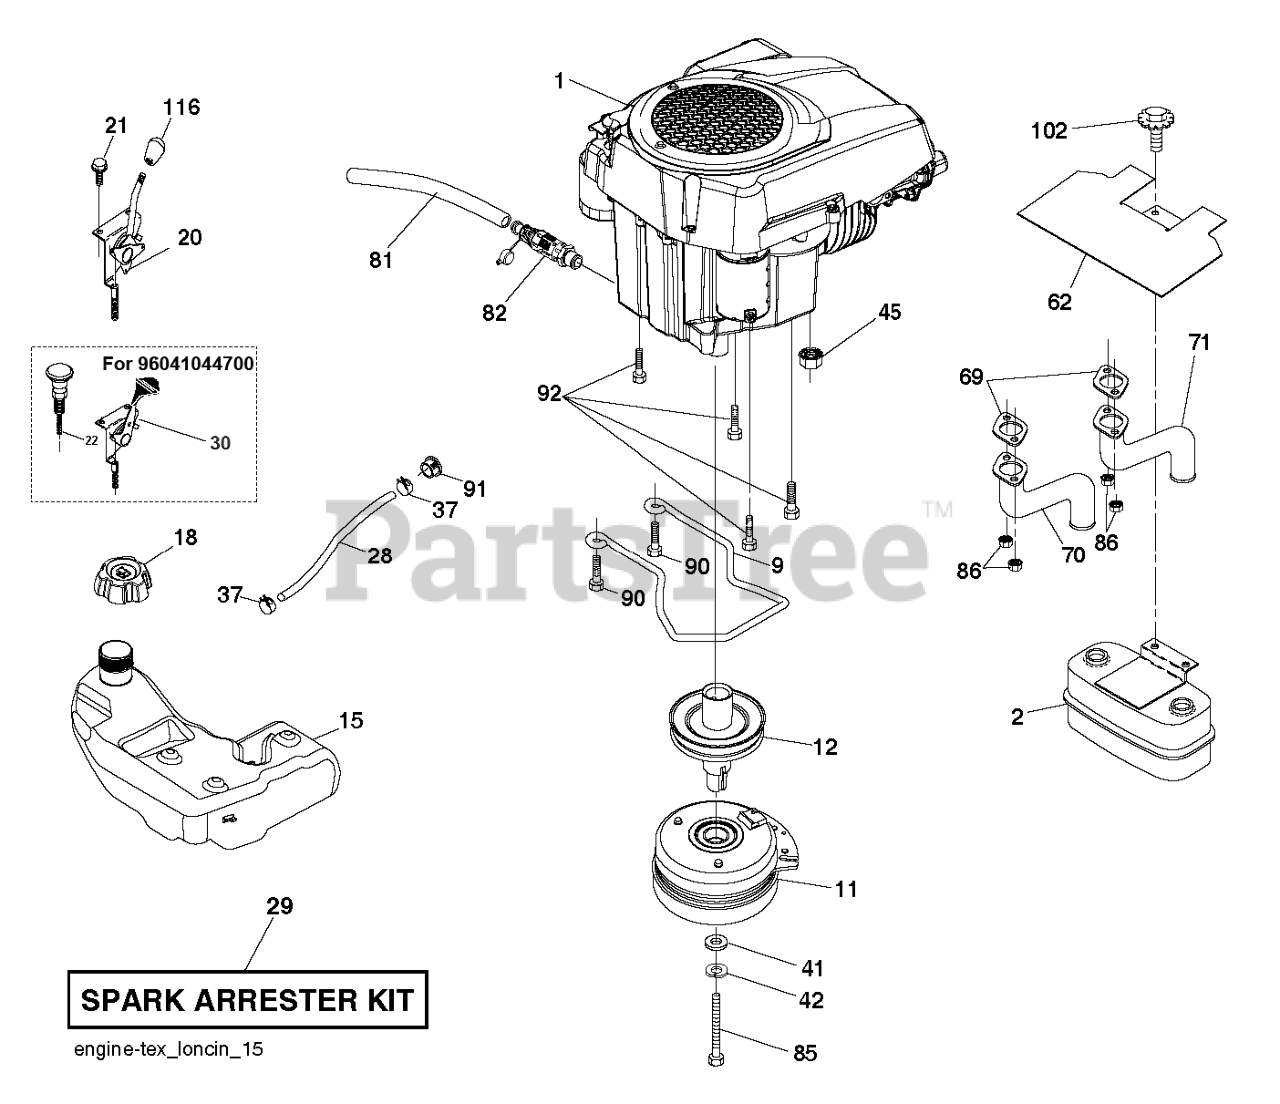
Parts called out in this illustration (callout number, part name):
2	MUFFLER.ASM.TWIN.MNTG.BRACKET
9	KEEPER.BELT.ENG.4.25"2.BLT.431
9	Keepers
11	CLUTCH. 5.0 PD. 2.5 OFFSET
11	CLUTCH.OGURA.4.4PD.GT1.5-EH13V
12	PULLEY.EXTENDED.SHAFT.GROUND
12	PULLEY.ENGINE.TUFFTORQ
15	TANK.FUEL.4GAL
15	FUEL.TANK.ASM.3.0GAL.REAR.2019
18	CAP ASSY FUEL 3" GRAY
18	CAP.ASSY.FUEL.3".N-EPA.GRY.498
18	FUEL CAP
20	CONTROL.THROTTLE/CHOKE.PRO.45
22	CONTROL, CHOKE
28	HOSE.1/4".LOW.PERM.FUEL.LN.60"
28	LINE.FUEL.64"REAR.EMIS
29	KIT.SPARK ARRESTOR 794945 B&S
30	CONTROL.THROTTLE.COBRA.BLACK
37	HOSE CLAMP
45	Hardware
45	NUT HEXAGON WITH FLANGE, SERRA
62	SHIELD.HEAT.MUFFLER
69	GASKET
70	TUBE.EXHAUST.LH.FR961/FR730
71	TUBE.EXHAUST.RH.FR961/FR730
81	TUBE, DRAIN OIL ASM.
82	VALUE.OIL.DRAIN
85	CLUTCH BOLT7/16-20X3.5 GR524HR
85	BOLT.HEX.7/16-20X5.GR5.GREEN
86	NUT.HEX.FLANGE.TOPLOCK
90	SCREW 3/8-16X1
91	BUSHING.1.375OD
92	SCREW 3/8-16X1
102	SCREW
116	KNOB - SHIFT
